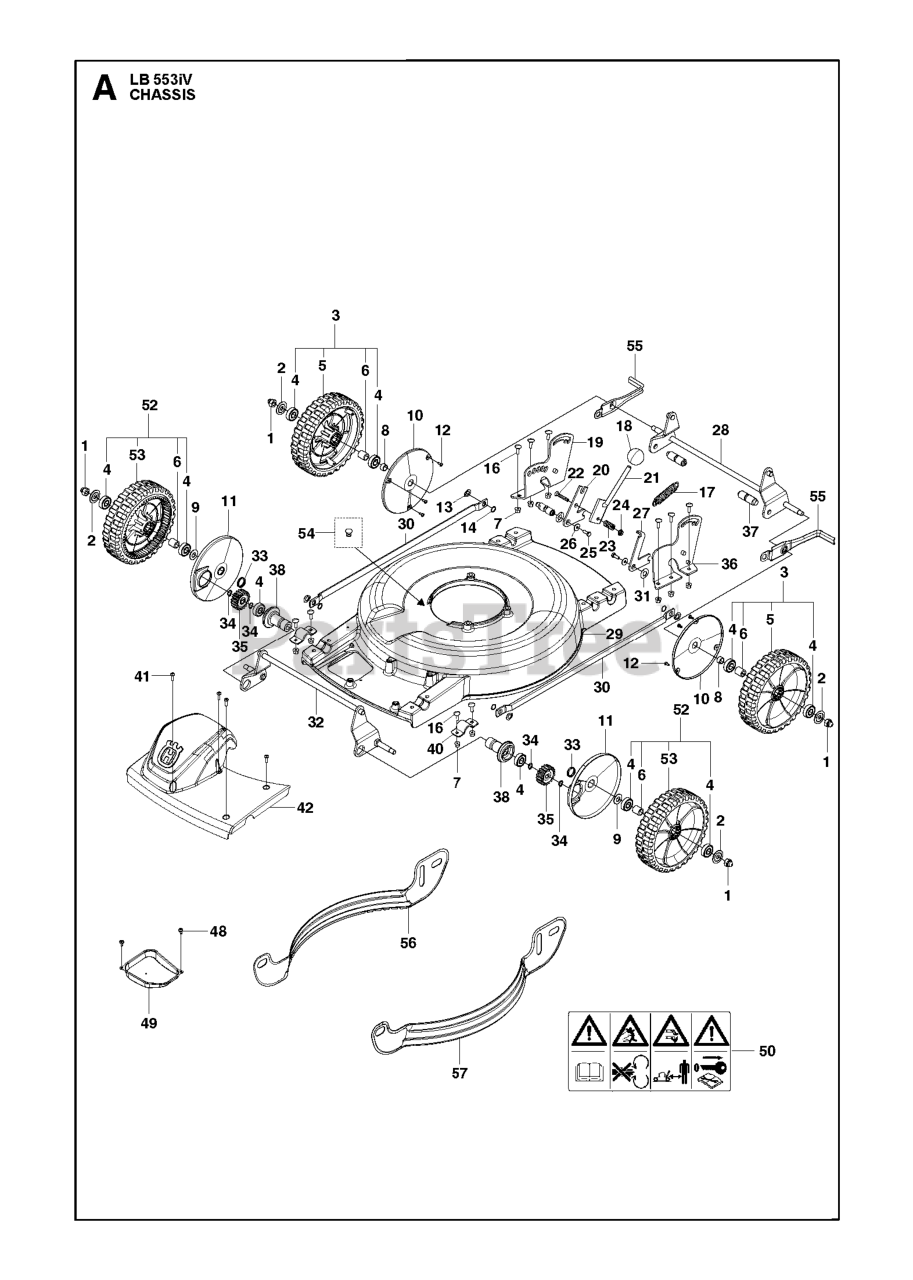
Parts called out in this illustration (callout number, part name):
1	NUT M53S / M48S
3	WHEEL PRO HUSQVARNA
4	BALL BEARING 6201-2RS/C3 W10
5	WHEEL ASSY PRO HUSQVARNA
6	SPACER PRO
7	LOCKING NUT FLANGE
8	SPACER M53 L=14
9	SPACER WASHER M53S / M48S
10	SHIELD PRO
13	RING M53S / M48S
14	RETAINING RING
17	SPRING M53 / M48
18	BALL M53 / M48
23	SPRING M53 / M48
24	FLANGE NUT
25	BOLT FLANGE M6X16
28	AXLE ASSY M53 PRO
33	SPRING M53 / M48
35	PINION PRO
48	SCREW ITXPANTT M5X10 ZPB (A00
52	WHEEL PRO, DRIVING HUSQVARNA
53	WHEEL ASSY PRO, DRIVING HUSQVA
